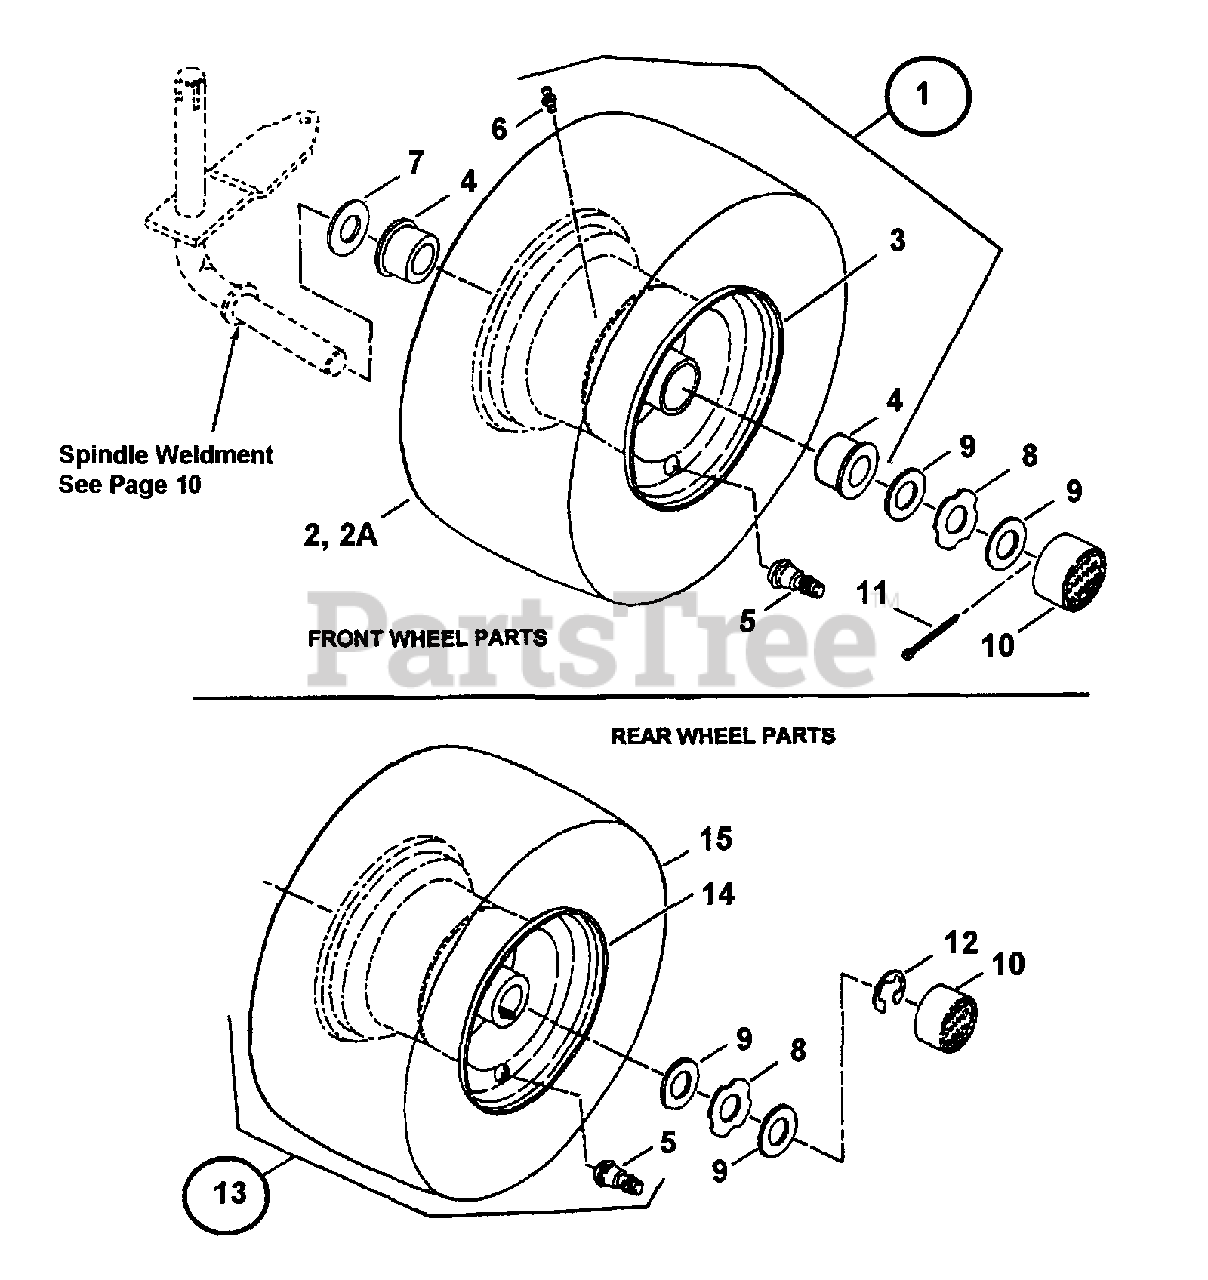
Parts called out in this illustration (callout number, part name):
1	ASSEMBLY, Front Tire & Rim
2	TIRE, 13 x 5.00
2A	TIRE, 15 x 6.00
3	RIM, 6.00 x 3.50
4	BEARING, Wheel
5	VALVE, Air (Snap-in)
6	FITTING, Lube 1/4-28 Tapered Thread
7	WASHER, Flat, 5/32 x 25/32" I.D. x 1-1/2" O.D.
8	WASHER, Hub-Cap Retaining
9	WASHER, Flat, 1/16 x 49/64 I.D. x 1-5/16" O.D.
10	HUB-CAP
11	COTTER-PIN, 5/32 x 1"
12	RING, External Retaining, 3/4"
13	ASSEMBLY, Rear Tire & Rim
14	RIM, 8 x 7.00
15	TIRE, 18 x 8.50-8
